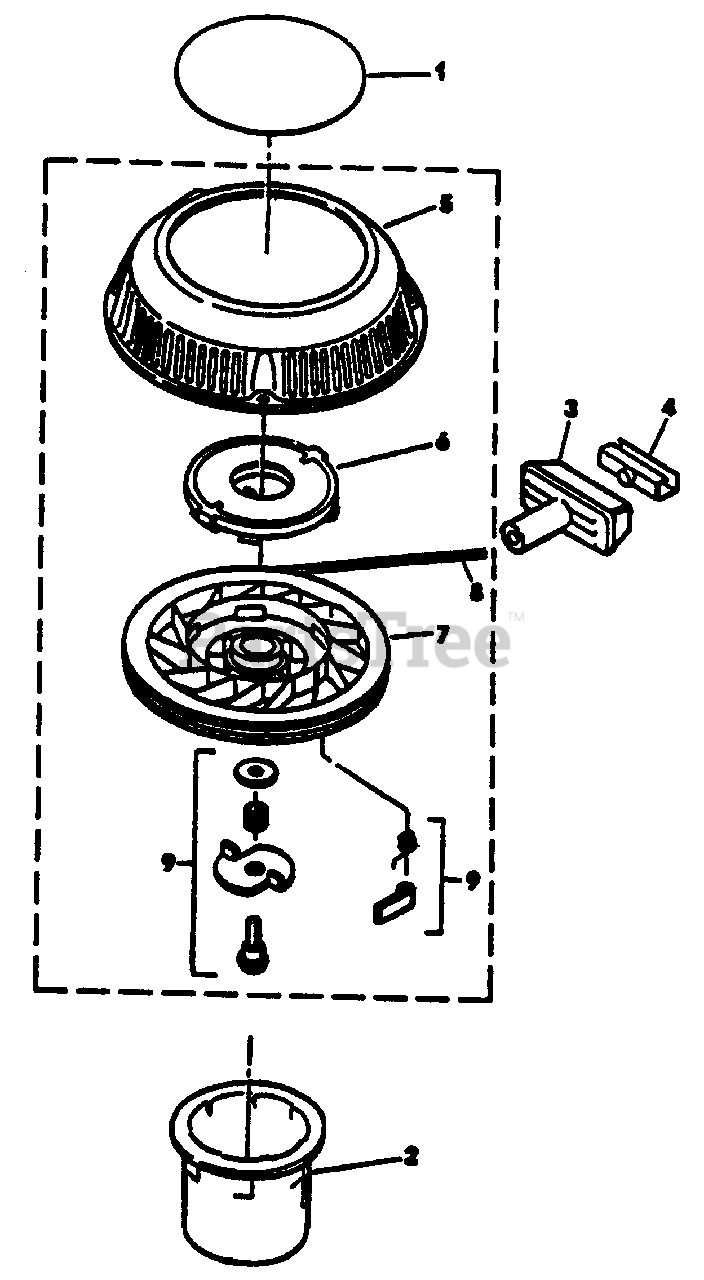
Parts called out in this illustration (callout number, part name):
1	Decal
2	Starter Hub
3	Starter Handle
4	Rope Clip-Starter Insert
5	Starter Housing and Shaft
6	Recoil Spring and Keeper
7	Pulley
8	Rope
9	Dog Kit
